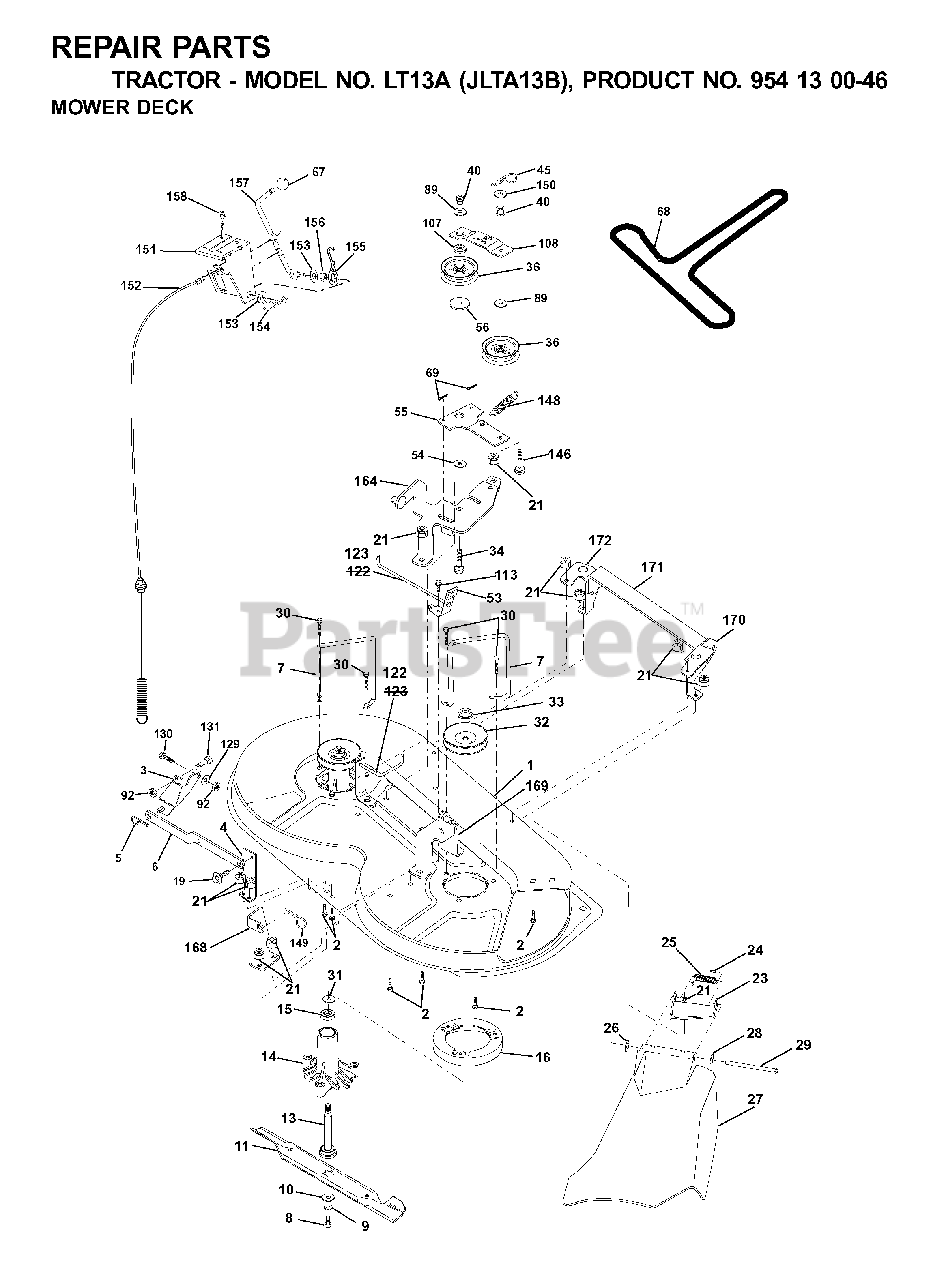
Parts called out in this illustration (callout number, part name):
2	BOLT
3	BRKT ASM SWAY BAR
5	RETAINER-SPRNG RB
6	REAR SUSP ARM
7	KEEPER LH
8	BLADE BOLT
9	LOCKWASHER
10	WASHER.BLADE
11	BLADE, HI-LIFT 36" PREMIUM
13	SHAFT ASM VENT
14	HSG MANDREL
16	STRIPPER, MWR ROUND
19	BOLT SHD 5/16-18
21	LOCKNUT
23	BRACKET ASM DEFLECTOR
24	CAP-SLEEVE LT
25	SPRING TORSION
26	NUT PUSH M
28	WASHER
29	HINGE ROD
30	SCREW THDROL ROLLING WASHER HD
31	WASHER
32	PULLEY, MANDREL
33	NUT
34	BOLT
36	FLAT IDLER PULLEY
40	LOCKNUT
45	RETAINER M
53	BRAKE ASSEMBLY
54	HARDENED WASHER
55	IDLER ARM
56	SPACER.RETAINER.MOWER
67	KNOB T (3/8 HOLE)
69	COTTER PIN
89	WASHER GT
92	NUT
107	SPACER.IDLER.ARM
108	STIFFENER.IDLER.ARM
113	SCREW LT
129	WASHER
130	BOLT
131	BOLT D
146	BOLT, CARRIAGE IDLER
148	IDLER RETURN SPRING
149	SPRING.RETAINER.YELLOW.ZINC
150	WASHER PM
151	BRACKET, CLUTCH CABLE
153	WASHER FLAT 3/8"
154	SPRING RETAINER
155	SPRING RETENTION LEVER
156	SPACER CLUTCH CABLE
157	ROD CLUTCH CABLE 3/8"
158	SCREW LT
171	BRACE
